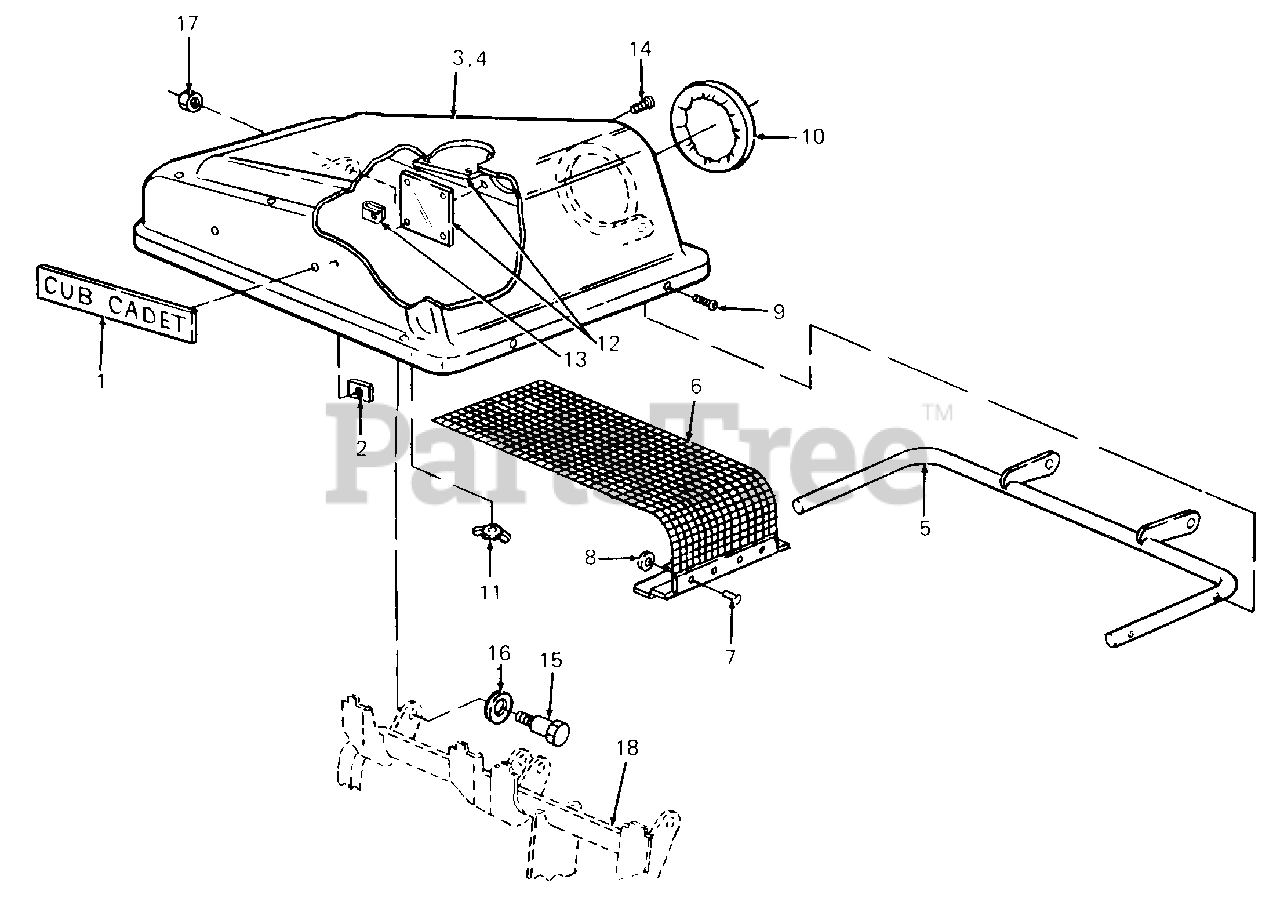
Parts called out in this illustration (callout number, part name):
1	Plaque, Logo w/Studs
2	Nut, Push-on Speed
3	Cover Ass'y, Grass Catcher
8	Washer, Flat, .218 x .62 x .063
9	Screw, Hex Wash. Hd. Tapp 1/4 x .50 Lg
10	Seal, Tube, 7.1 ID
11	Twist Fastener, Zip
12	Plate, Plastic, 1/8 Thk x 5.62 Sq
13	Nut, U-Type Speed
14	Screw, Truss Mach., #10 x .50 Lg
15	Screw, Shld
16	Washer, Bell, .505 x 1.0 x .075 Thk
17	Nut, Hex Flanged Lock, 3/8-16
18	Tube Ass'y, Catcher Support
